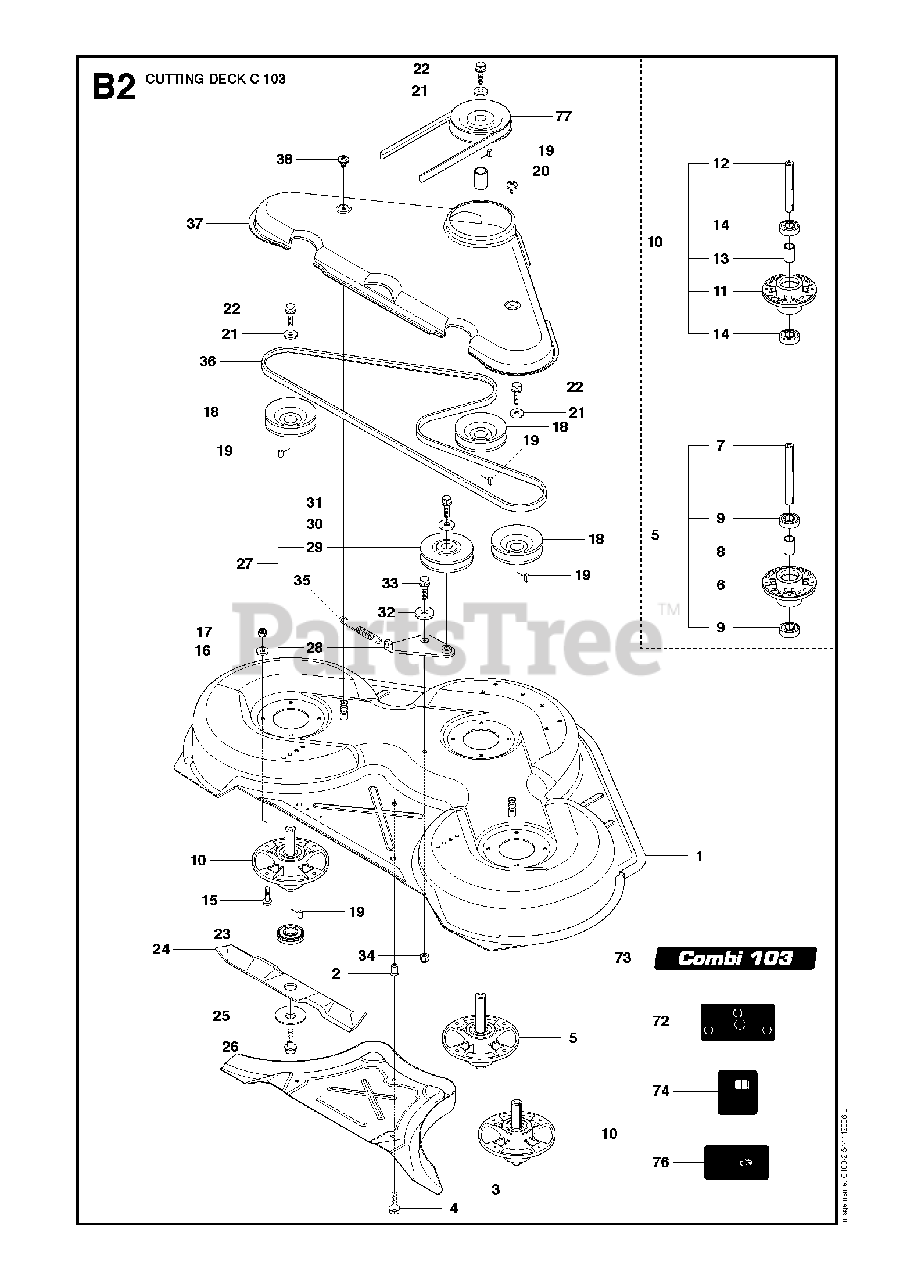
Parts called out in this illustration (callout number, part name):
1	CUTTING DECK
5	BLADE HOUSING ASSY
6	BEARING HOUSING
7	SHAFT
8	SPACING SLEEVE
9	BEARING
10	BLADE HOUSING ASSY
11	BEARING HOUSING
12	SHAFT
13	SPACING SLEEVE
14	BEARING
16	WASHER BRB 8.4X17
17	LOCKNUT M8
24	BLADE
25	WASHER
27	BELT TENSIONER ASSY
28	BELT TENSIONING ARM
29	PULLEY
30	SPACER
31	BOLT
32	WASHER
34	LOCKNUT M8
36	BELT
